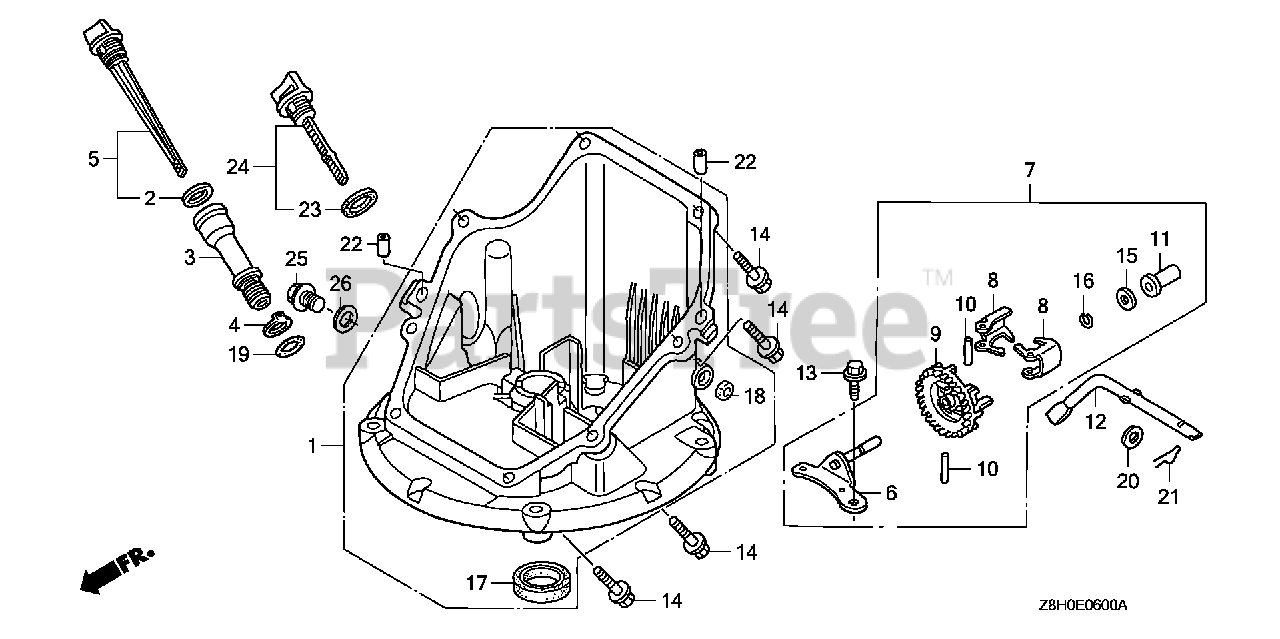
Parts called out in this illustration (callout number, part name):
1	PAN ASSY., OIL
6	SHAFT, GOVERNOR HOLDER
7	GOVERNOR ASSY.
8	WEIGHT, GOVERNOR
9	HOLDER, GOVERNOR WEIGHT
10	PIN, GOVERNOR WEIGHT
11	SLIDER, GOVERNOR
12	SHAFT, GOVERNOR ARM
13	BOLT, FLANGE (6X14) (CT200)
14	BOLT, FLANGE (6X25) (CT200)
15	WASHER, THRUST (6MM)
16	CLIP, GOVERNOR HOLDER
17	OIL SEAL (28X41.25X6)
20	WASHER, PLAIN (6MM)
21	PIN, LOCK (8MM)
22	PIN, DOWEL (8X20)
23	GASKET, OIL FILLER CAP
24	GAUGE ASSY., OIL LEVEL
